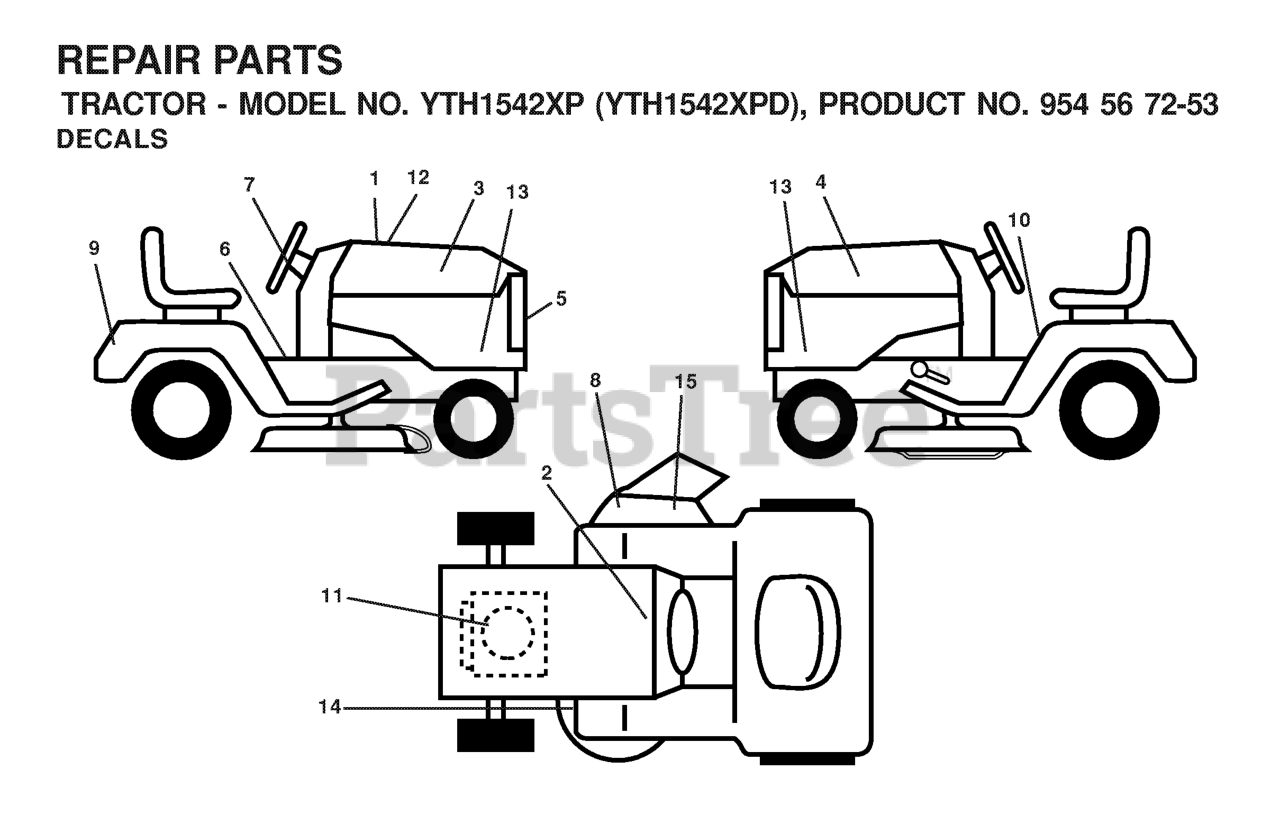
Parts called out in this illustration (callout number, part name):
1	DECAL HOOD CUST. RESP.
2	DECAL BTRY SYMBOLS
5	DECAL.GRILLE.HUSQ
7	DECAL.WHEEL.STEERING.HUSQ.PERM
8	DECAL.WARN.KEEP.HAND.AWAY
9	DECAL, FENDER
10	DECAL FENDER DANGER
13	DECAL HOOD SIDES
14	DECAL V BELT SCHEMATIC
15	DECAL DECK "B" 42"
